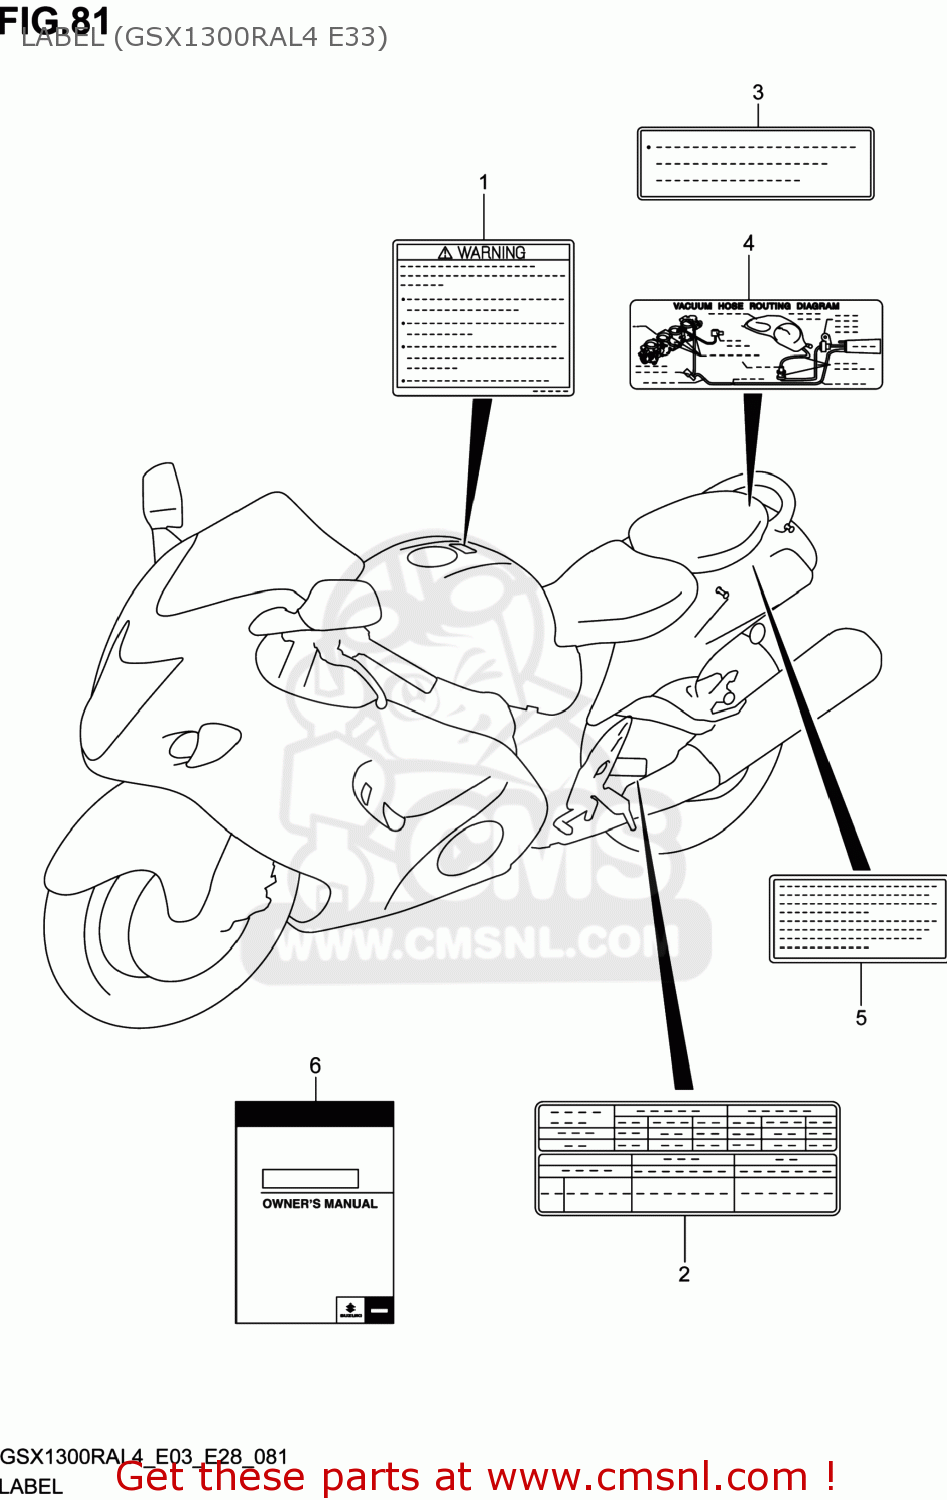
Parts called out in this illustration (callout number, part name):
1	LABEL,GENERAL WARNING
2	LABEL,TIRE INFORMATION
3	LABEL,FUEL INFORMATION
4	LABEL,VACUUM HOSE ROUTING
5	LABEL,MANUAL NOTICE
6	MANUAL,OWNER'S
